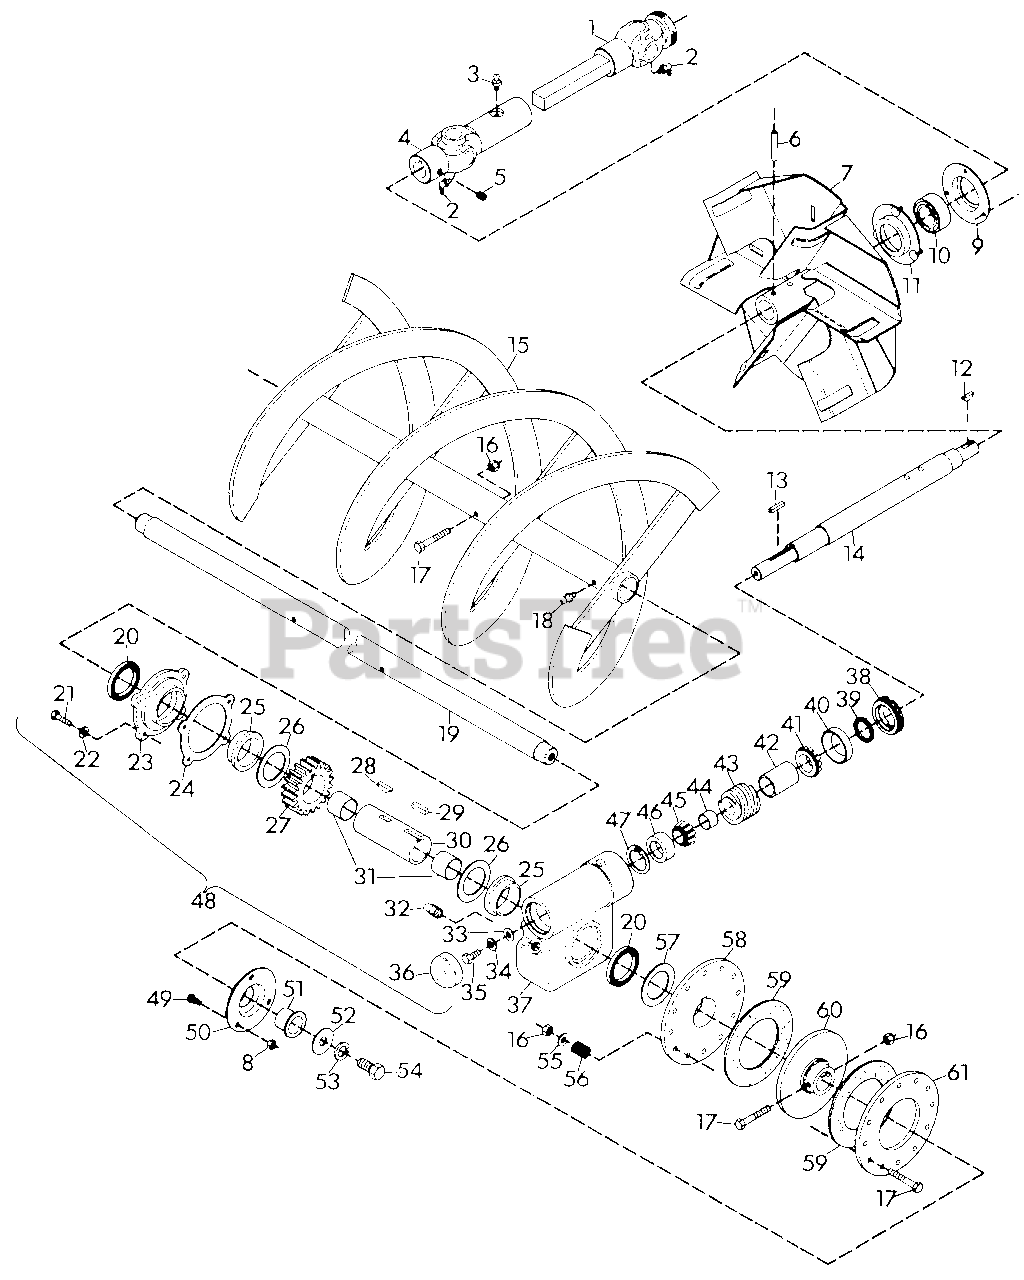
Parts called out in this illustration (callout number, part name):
1	SHAFT, PROP. SQ. BAR
2	FITTING, LUBE 90 DEGREE
3	FITTING, LUBE 1/4-28
4	U-JOINT, FEMALE
5	SCREW, SET 3/8-16X.375
6	PIN, ROLL 5/16X1.75
7	FAN
8	NUT, LOCK 1/4-20
9	BEARING, FLANGE
10	BEARING, BALL
11	BEARING, FLANGE
12	KEY, WOODRUFF 3/16X7/8 HRD #11
13	KEY, STRAIGHT SAE 1035
14	WORM SHAFT
15	RIGHT RAKE - 40"
15	RIGHT RAKE - 48"
15	LEFT RAKE - 40"
15	LEFT RAKE - 48"
16	NUT, LOCK 5/16-18
17	BOLT, HEX 5/16-18X2.00
18	FITTING, LUBE 1/4-28
19	40" RAKE SHAFT
19	48" RAKE SHAFT
20	SEAL
21	BOLT, HEX 1/4-20X.875
22	WASHER, LOCK 1/4 EXT TH TYA
23	COVER, GEARCASE
24	GASKET
25	BUSHING, FLANGE 1.62X1.87X11
26	WASHER, 1.625X2.50X.012
27	GEAR, WORM
28	KEY, FEATHER
29	KEY, STRAIGHT
30	GEARCASE SHAFT
31	BUSHING, SLEEVE
32	PIPE PLUG
33	WASHER, FLAT .344X.688X.065
34	WASHER, LOCK 5/16 SP
35	BOLT, HEX 5/16-18X.75
36	CAP, DUST
37	GEARCASE
38	ADJUSTMENT PLUG
39	SEAL
40	BEARING CUP
41	BEARING CONE
42	BEARING SPACER
43	WORM
44	SPACER, BEARING
45	BEARING CONE
46	BEARING CUP
47	RING, SNAP INTERNAL 1.781
48	GEARCASE ASSEMBLY
49	BOLT, RIB NECK 1/4-20X.5
50	SUPPORT, BEARING
51	BUSHING, FLANGE 1X1.12X.625
52	WASHER, FLAT .515X1.441X.1
53	WASHER, LOCK 1/2 SP HEAVY
54	BOLT, HEX 1/2-13X1
55	WASHER, FLAT
56	SPRING, COMPRESSION
57	WASHER
58	DRIVER
59	FRICTION DISC
60	DRIVER PLATE
61	PRESSURE PLATE
